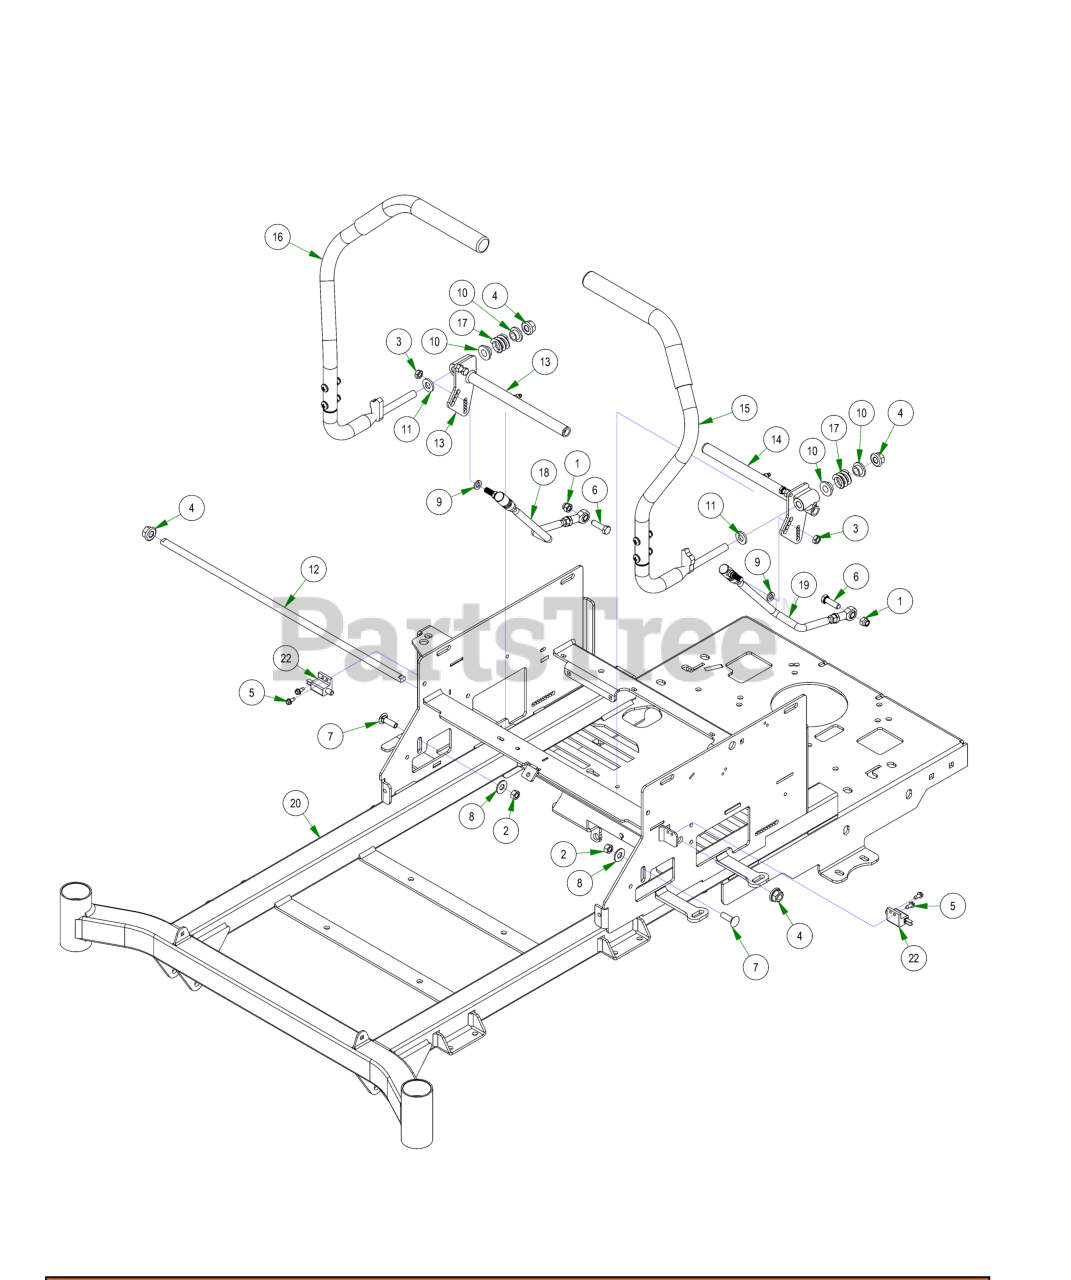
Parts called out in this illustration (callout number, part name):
1	3/8-16 NYLON INSERT LOCKNUT ZINC
2	3/8-16 HEX NUT ZINC
3	3/8-24 HEX NUT ZINC YELLOW
4	1/2-13 NYLON INSERT FLANGE LOCKNUT ZINC
5	12-24 X 1/2 HEX WASHER UNLSOT F TCS ZINC
6	3/8-16 X 1-1/4 HEX CAP SCREW (GR.5) ZINC
7	3/8-16 X 1-1/4 CARRIAGE BOLT ZINC
8	3/8 FLAT WASHER USS (1" OD) ZINC
9	3/8 SPLIT LOCKWASHER ZINC
10	.525 ID SHOULDER WASHER NYLON
11	.505 ID X 1.000 OD X .125 THICK FLAT WASHER NYLON
12	2021 Maverick Steering Actuator Rod
13	2021 Maverick Drive Arm Actuator RH Assembly
14	2021 Maverick Drive Arm Actuator LH Assembly
15	ZT Steering Arm-Left
16	ZT Steering Arm-Right
17	Drive Lever Spring
18	Push Rod-Right
19	Push Rod-Left
20	2024 MZ 42-48 Frame
21	2024 MZ-Avenger 54-60 Frame
22	Safety Switch
